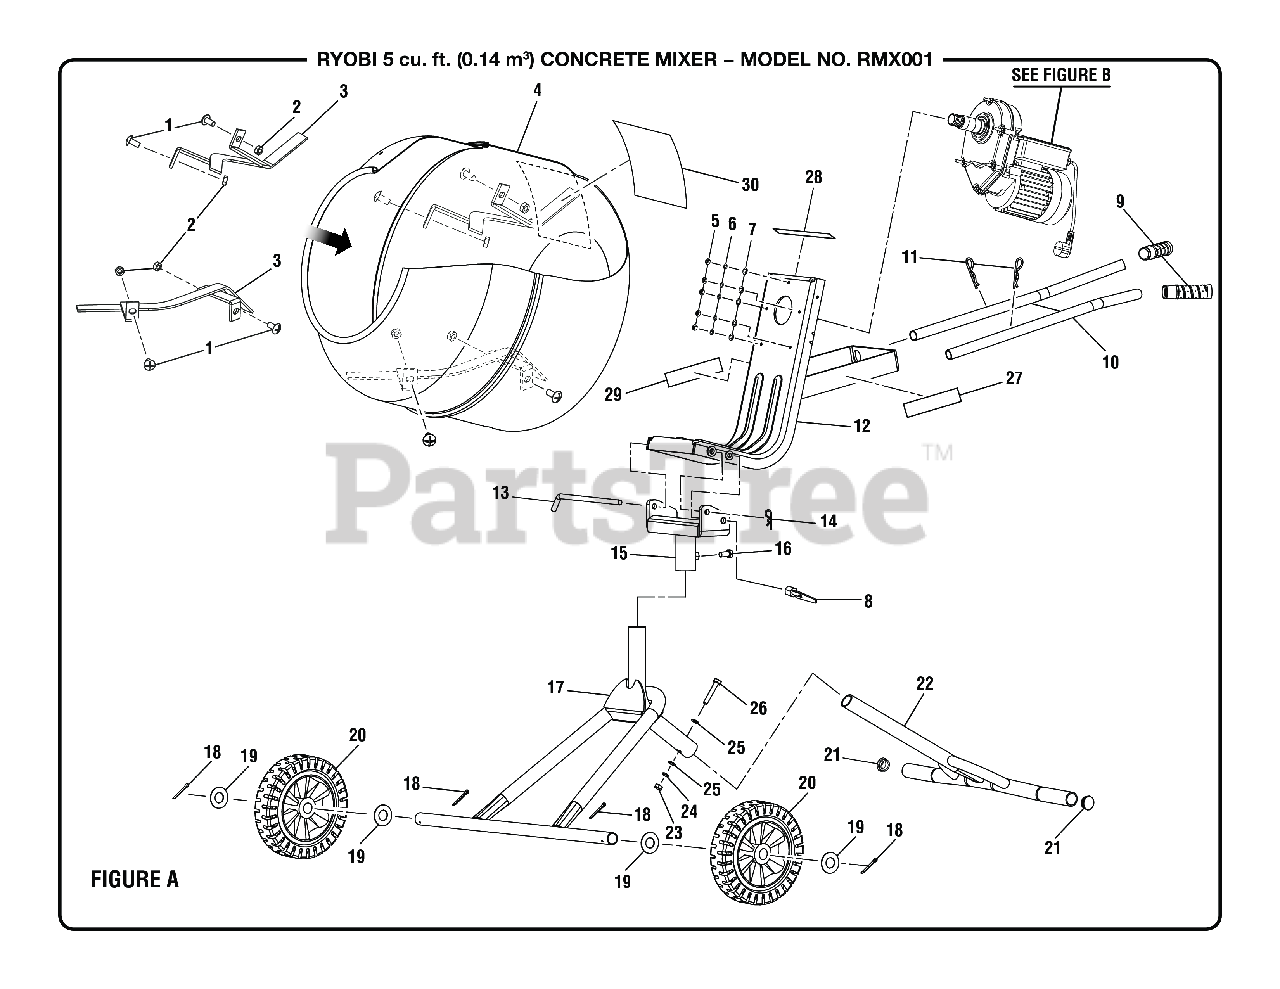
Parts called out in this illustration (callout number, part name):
1	Screw (M12 x 25 mm, Pan Hd.)
2	Hex Nut (M12)
3	Mixing Tine
4	Drum (Inc. Key No. 35)
5	Hex Nut (M6)
6	Lock Washer (M6)
7	Washer (M6)
8	Lock Handle Assembly
9	Handle Grip
11	Hitch Pin (3.5)
12	Drum and Motor Bracket (Inc. Key Nos. 32-34)
13	Pivot Pin (12 × 240)
14	Hitch Pin (3)
15	Swivel Bracket
16	Bolt (M10 x 25 mm)
18	Cotter Pin (6 × 50)
23	Hex Nut (M10)
24	Lock Washer (M10)
25	Cup Washer (M10)
26	Bolt (M10 x 60 mm, Hex Hd.)
27	Instruction Label
28	Icon Warning label
